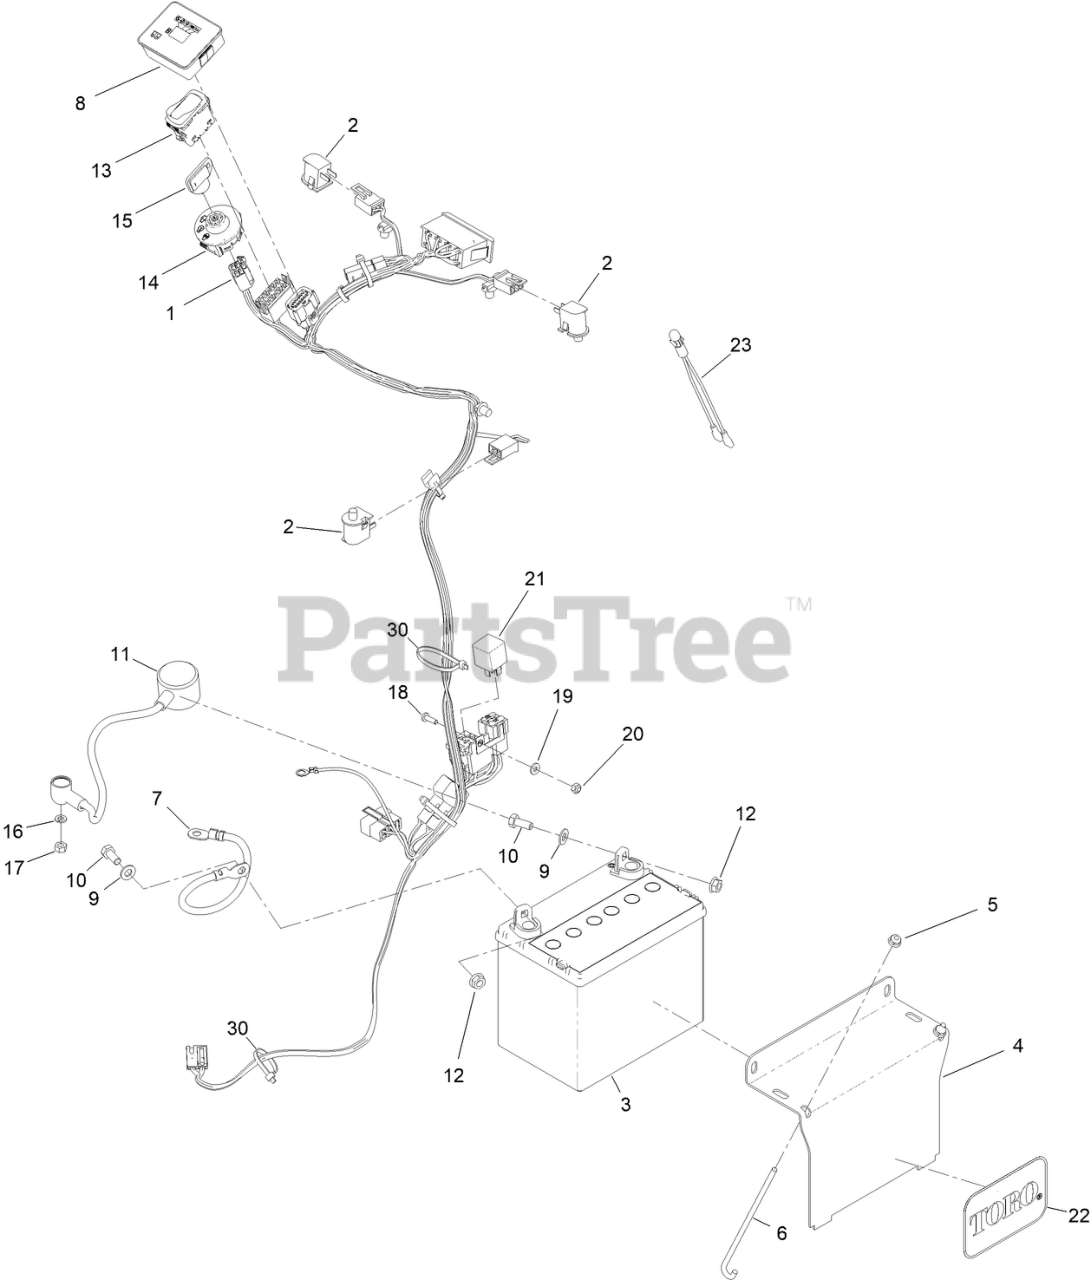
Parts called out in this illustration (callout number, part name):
1	HARNESS-WIRE, GRANDSTAND
2	SWITCH-BAIL
3	BATTERY-DRY
4	BRACKET-HOLD DOWN, BATTERY
5	NUT-HF
6	BOLT-HOLDDOWN
7	CABLE-BATTERY, BLACK
8	MODULE-METER, HOUR
9	WASHER-PLAIN
10	SCREW-HH
11	CABLE-BATTERY, POSITIVE
12	NUT-HHF, SMOOTH
13	SWITCH-ROCKER, (ON)-ON-OFF
14	SWITCH-IGNITION
15	KEY-IGNITION
16	WASHER-LOCK
17	NUT-HEX
18	SCREW-PPH
19	WASHER-FLAT
20	NUT-LOCK, NI
22	DECAL
23	INDICATOR-LED, RED
30	TIE-CABLE
99	KIT-GS WIRE HARNESS, KOHLER
